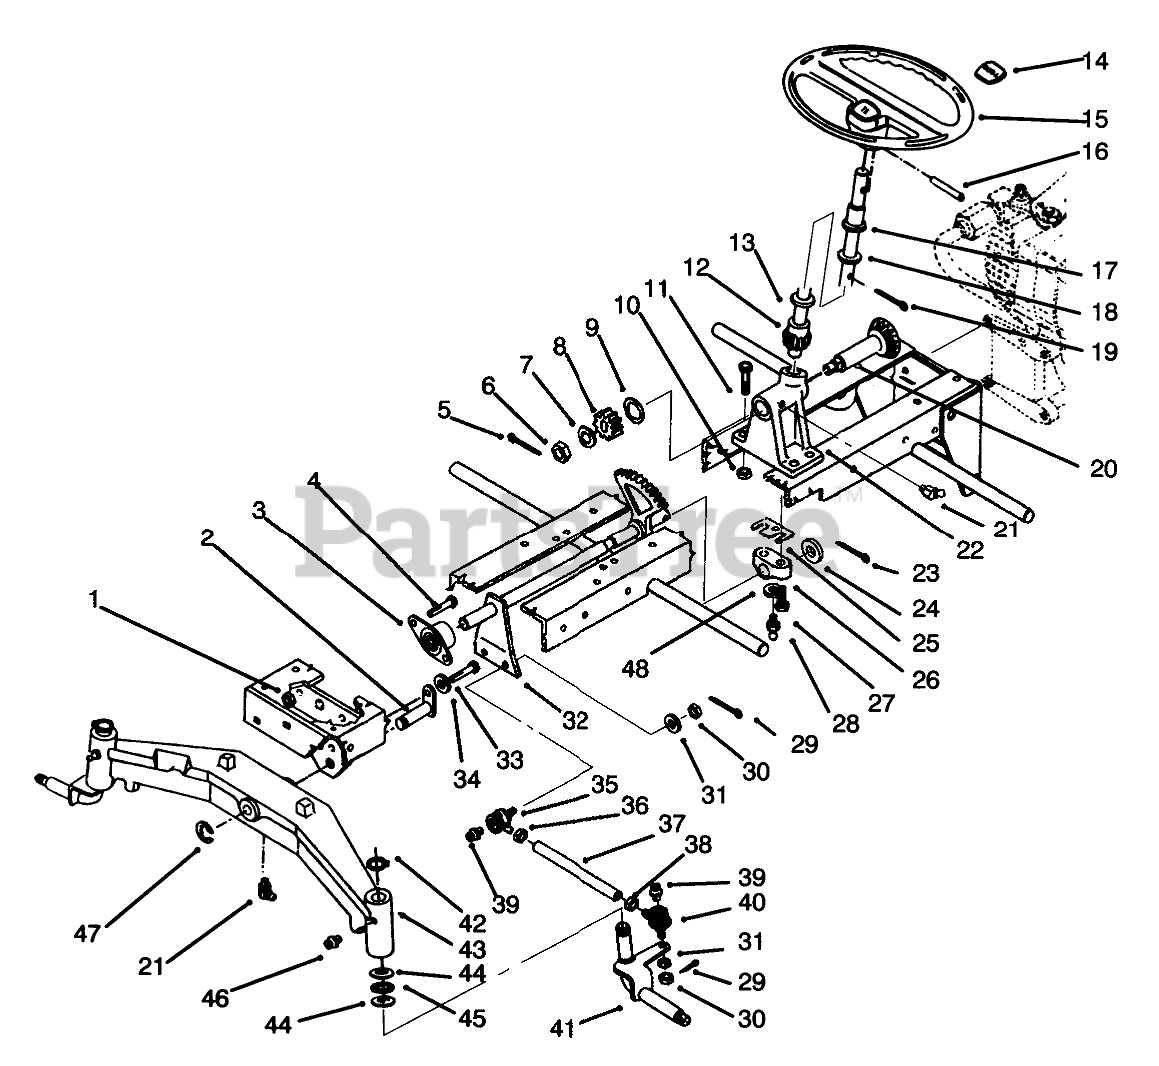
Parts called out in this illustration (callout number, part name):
1	NUT-LOCK, NI
2	PIN AND PLATE ASM
3	BEARING-FLANGED
4	SCREW-HH
5	PIN-COTTER
6	Nut
7	WASHER-FLAT
8	PINION-SPUR
9	WASHER
10	NUT-LOCK, NI
11	SCREW-HH
12	WLDMT-STRG SHAFT
13	O-RING
14	STRG-WHL INSERT TORO
15	Steering Wheel (Incl. Ref. #14)
16	PIN-ROLL
17	BEARING-FLANGED
18	WASHER-SHIM
19	PIN-COTTER
20	WLDMT-C SHAFT
21	FITTING-GREASE
22	Steering Support
23	PIN-COTTER
24	WSHR-.765X1.125X.060
25	SHIM-.010
26	BLOCK-BEARING
27	Bolt
28	ZERK FITTING
29	PIN-COTTER
31	WASHER
32	Shaft
33	SCREW-HH
34	WASHER-LOCK
35	Tie Rod End-Thread RH (Incl. Ref. #30)
36	NUT-JAM
37	Tube
38	NUT-HEX JAM 9/16-18
39	FITTING-GREASE
40	Tie Rod End-Thread LH (Incl. Ref. #30)
41	Spindle
42	RING-RETAINING
43	Axle-Front
44	WASHER-THRUST
45	BEARING-THRUST
46	FITTING-GREASE
47	E-RING
48	WASHER-LOCK
